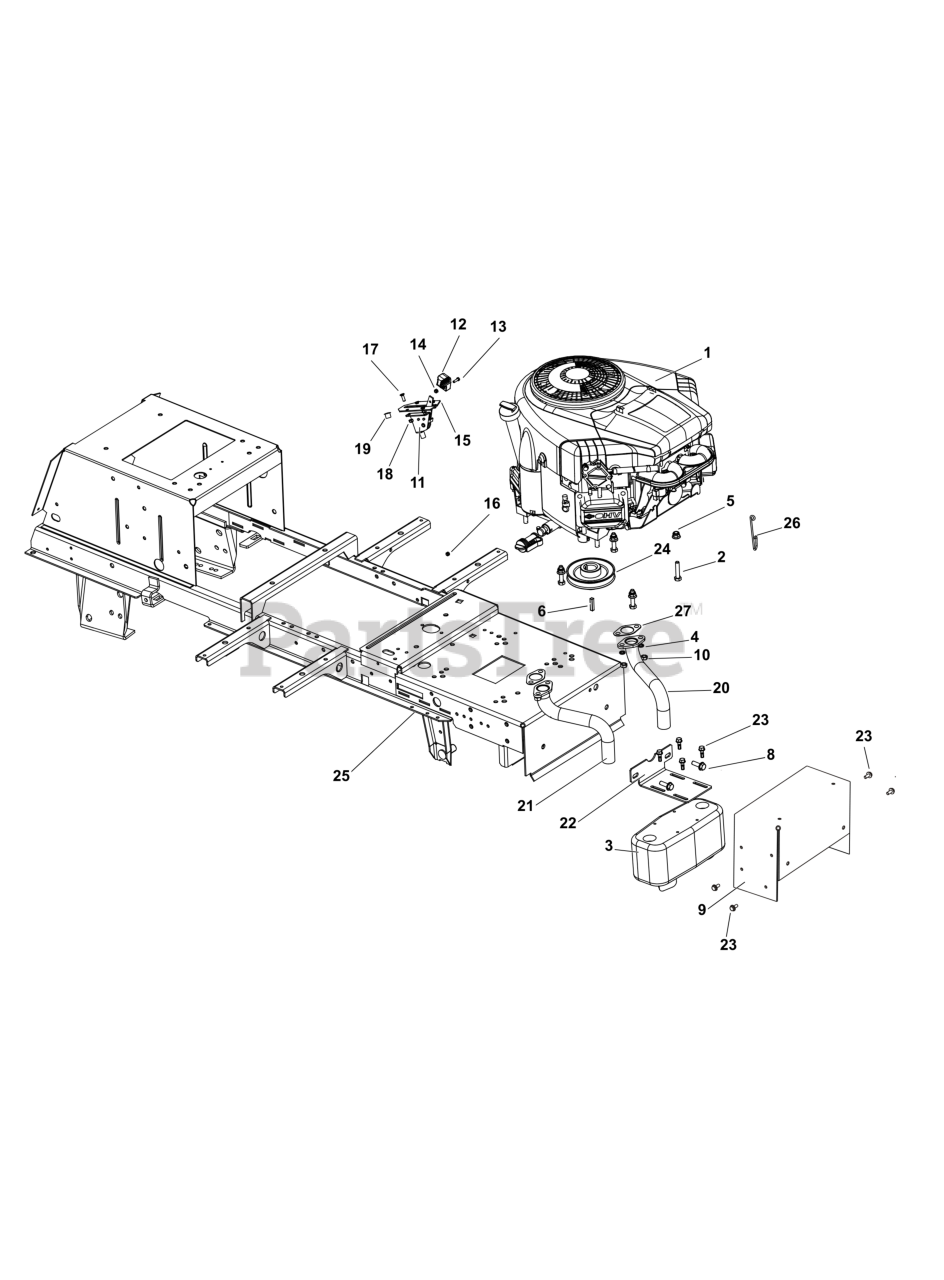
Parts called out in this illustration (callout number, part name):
1	ENGINE, B&S 8270 Professional Series
6	KEY, Drive Pulley
11	LEVER, THROTTLE
12	LEVER, THROTTLE
15	PLATE, Reinforcement
20	MANIFOLD, Exhaust
21	MANIFOLD, Exhaust
27	GASKET, Exhaust
